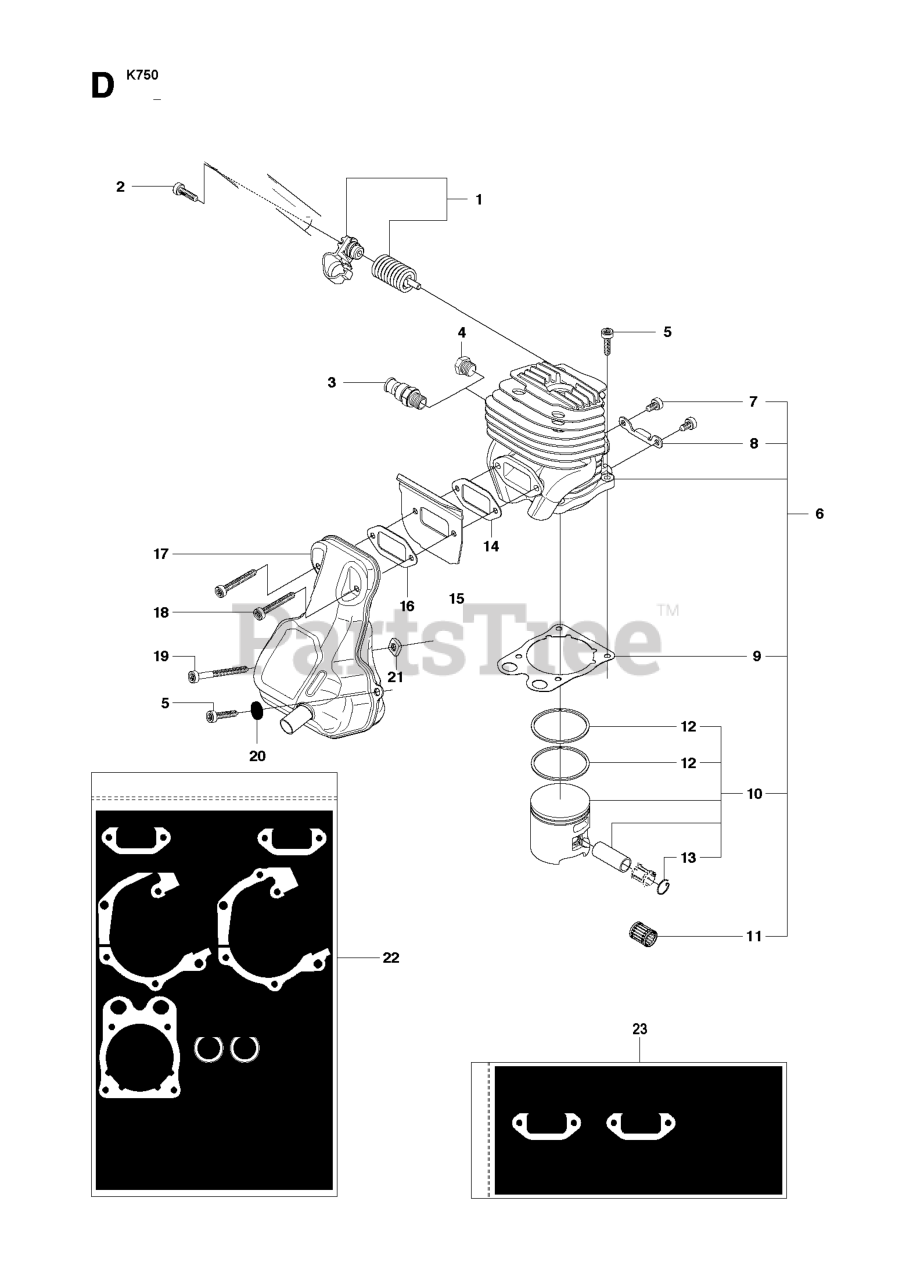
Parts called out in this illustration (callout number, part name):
1	SPRING HOLDER
3	DECOMPRESSION VALVE
4	CYLINDER PLUG
6	CYLINDER ASSY
10	PISTON CPL.
11	SUPPORT BUSHING
12	%PISTON RING
13	WRIST PIN CLIP
16	GASKET
17	MUFFLER - NO MOUNTING KIT
20	DOUBLE WASHER
22	GASKET KIT
23	MUFFLER, MOUNTING KIT K750
27	SEALING RING
28	RP GASKET CARBURETOR
